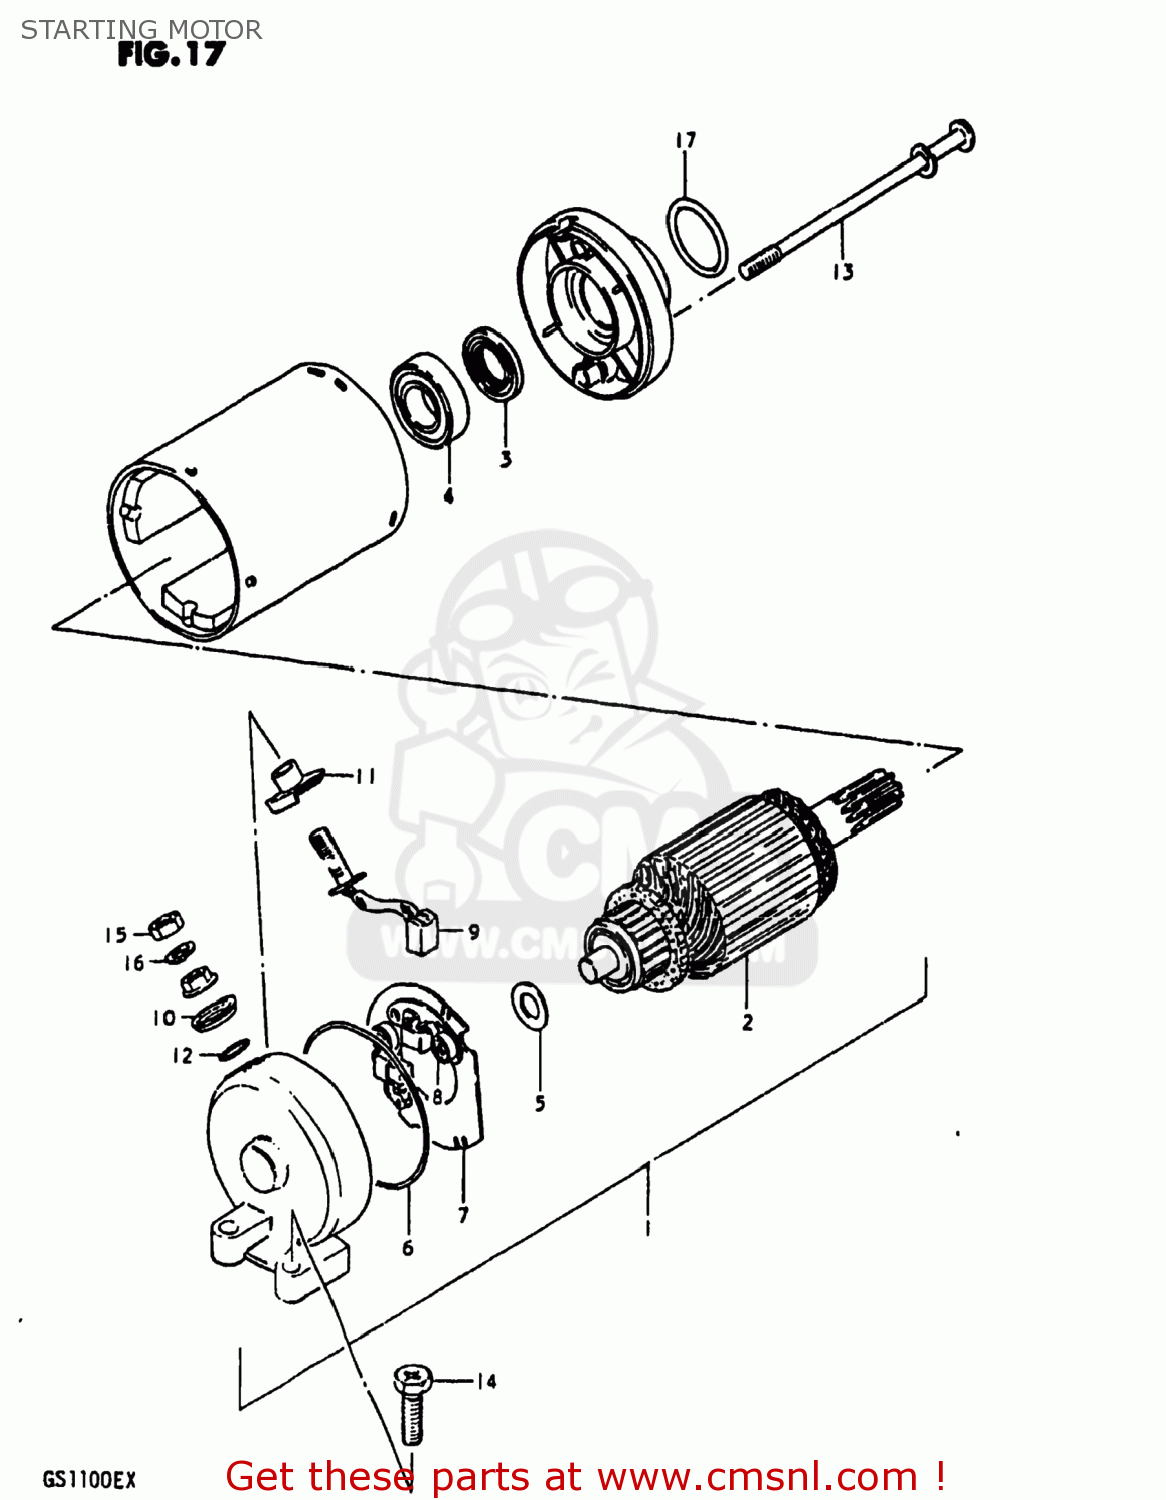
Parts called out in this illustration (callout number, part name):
1	MOTOR ASSEMBLY,STARTING
2	ARMATURE
3	SEAL,OIL
4	BEARING
5	SHIM,ARMATURE
6	O RING
7	HOLDER,BRUSH
8	SPRING
9	BRUSH (+)
10	BUSHING (1)
11	BUSH,NO.2
12	O-RING
13	BOLT,STARTING MOTOR HOUSING
14	SCREW (6X25)
15	NUT 6MM
16	LOCK WASHER
17	O RING(D:2,ID:24.5)
